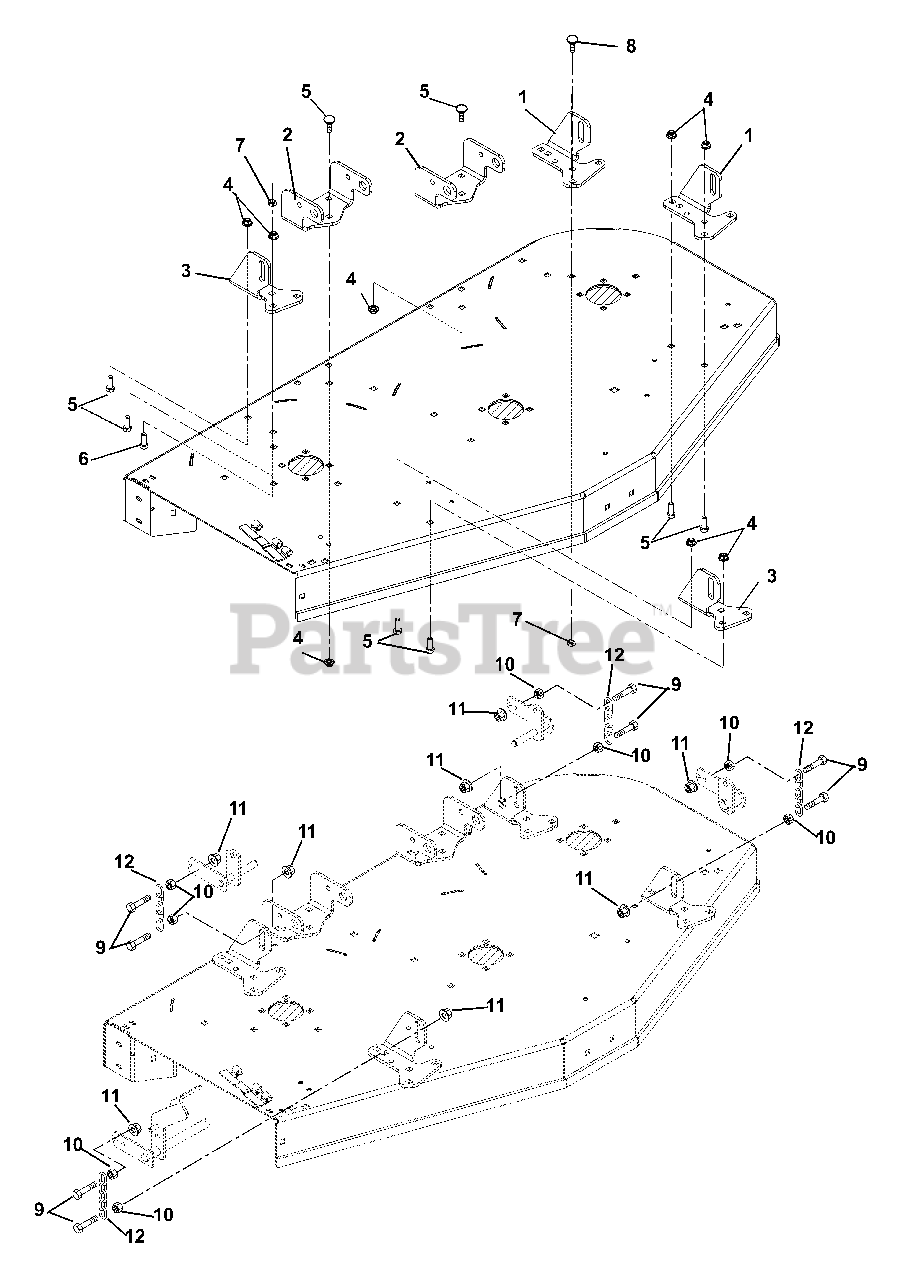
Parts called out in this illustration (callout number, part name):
1	Bracket, Deck Hanging
2	Bracket, Deck Mounting
3	Bracket, Deck Hanging
4	Nut, 3/8-16 Flange Nyloc
5	Bolt, Round Head Square Neck .38-16 x 1.00 Grade 5
6	Bolt, Round Head Square Neck .38-16 x 1.25 Grade 5
7	Nut, Locking Jam .375-16
8	Bolt, Round Head Square Neck .38-16 x .75 Grade 5
9	Bolt, Hex M12-1.75 x 55 Grade 5
10	Nut, Spinlock Flange M12-1.75
11	Nut, Locking Top Flange M12-1.75
12	Chain, Link
